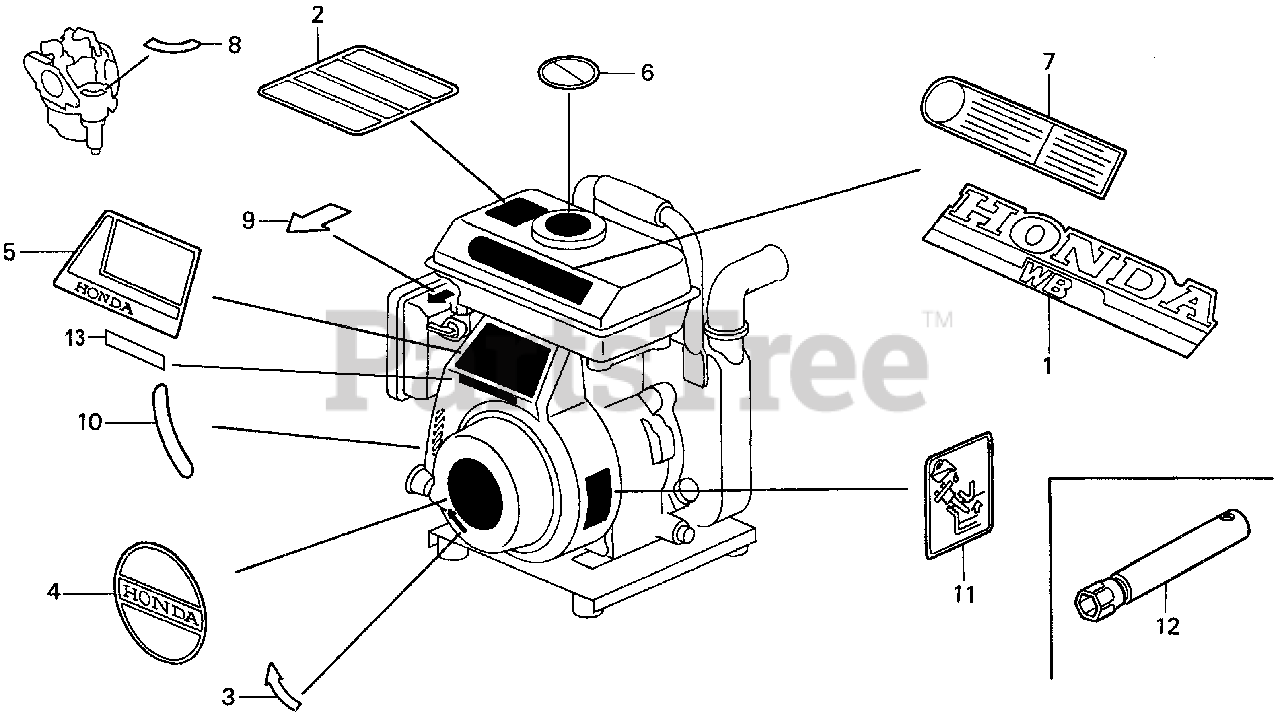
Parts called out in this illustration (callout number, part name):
1	MARK (WB15)
2	MARK, CAUTION (PUMP)
4	EMBLEM (EXP)
6	MARK, CAUTION (EXTERNAL)
8	MARK (EXTERNAL)
9	MARK, CHOKE
10	MARK, THROTTLE (ENGLISH/FRENCH)(GERMAN)
12	WRENCH, SPARK PLUG (NOT AVAILABLE)
13	LABEL (E-SPEC)
